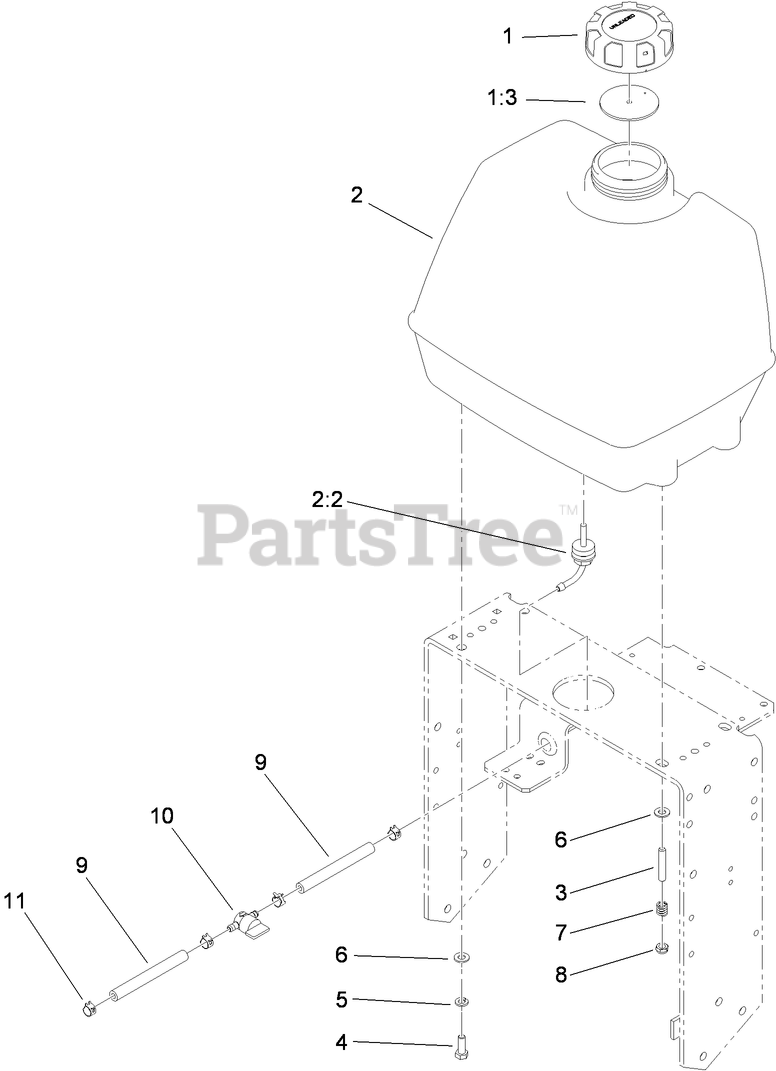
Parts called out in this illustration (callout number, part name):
1	GAS CAP ASM
1:3	GASKET-CAP, GAS
2	FUEL TANK ASM
2:2	FITTING-FUEL, BULKHEAD
3	STUD-THREADED
4	SCREW-HH
5	WASHER-LOCK
6	WASHER-PLAIN
7	SPRING-TANK, FUEL
8	NUT-LOCK, NI
9	HOSE-FUEL
10	VALVE-FUEL
11	CLAMP-HOSE
